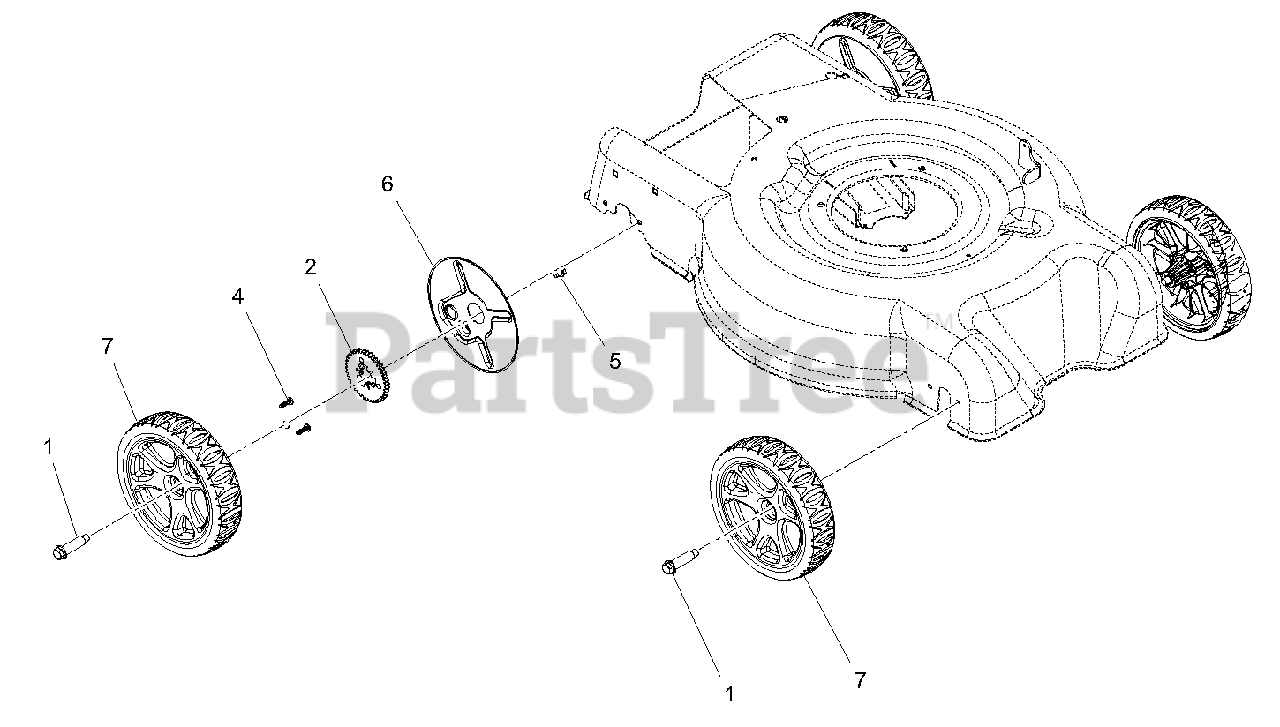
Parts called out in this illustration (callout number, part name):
1	BOLT, WHEEL SHOULDER
2	GEAR, WHEEL
4	SCR-TAP 12-14X.75PLSTITE @BLZC
5	@SCR-TAP .25-20X.37 HWH YWZ TR
6	COVER, WHEEL-ARIENS LM SPECIAL
7	WHEEL-8.5" WBLM ASSY
